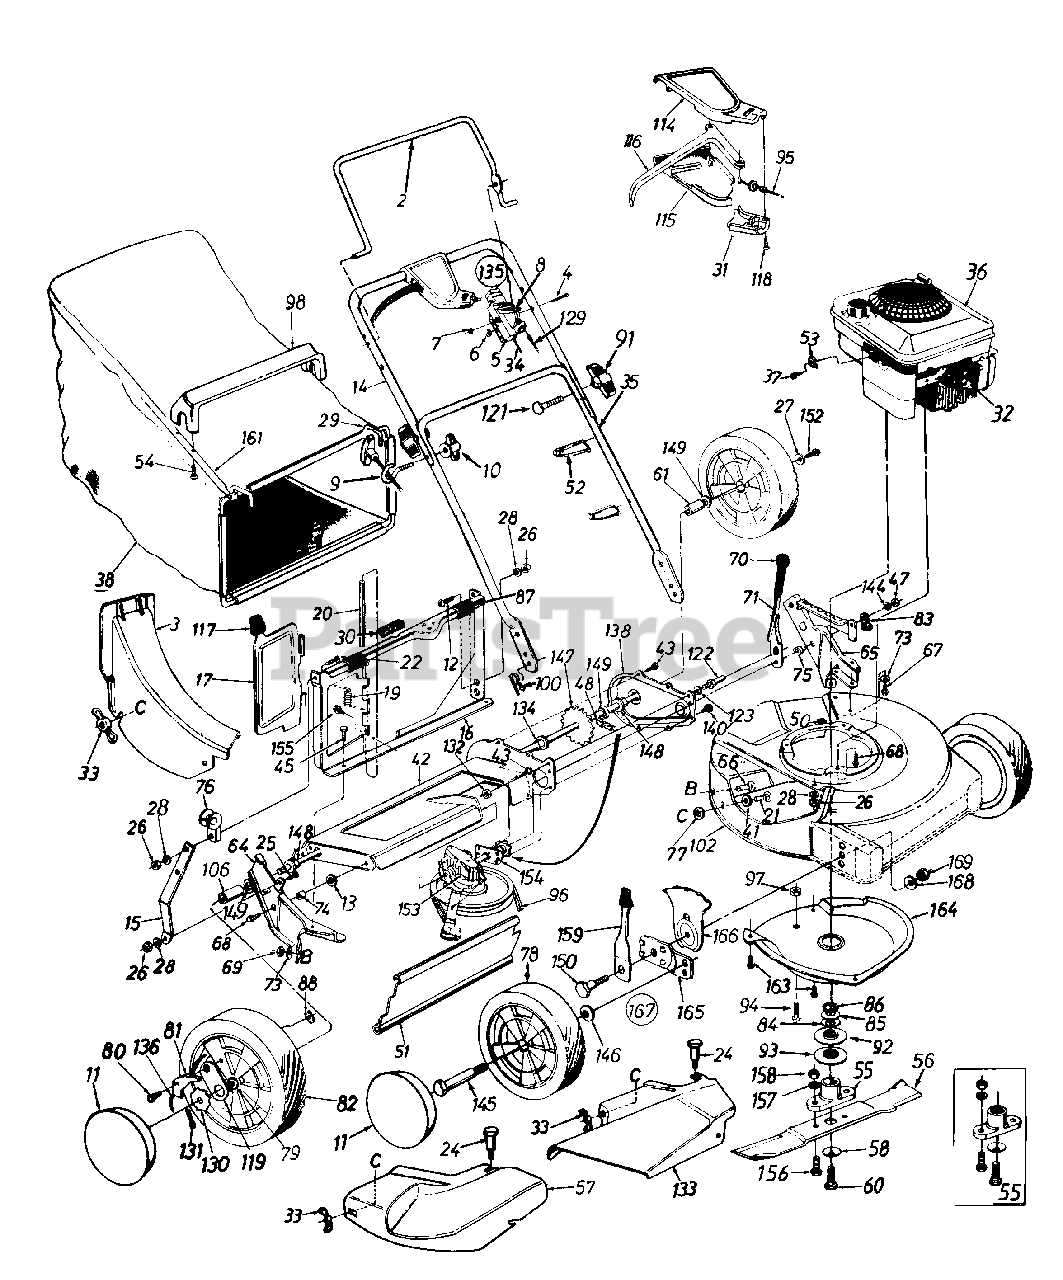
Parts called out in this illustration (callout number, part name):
3	Rear Discharge Chute Ass'y.
4	Oval C-Sunk Scr.
5	Throttle Body
6	Spr. Wash. .66" I.D.
7	Hex L-Nut 1/4-20 Thd.
8	Throttle Lever
9	Rope Guide
10	Wing Nut 1/4-20 Thd.
11	Hub Cap
12	Truss Mach. Scr. 1/4-20 x .62"
13	FL-Wash. .383" I.D. x 1" O.D.
20	Pivot Pin
21	Carriage Bolt 1/4-20 x .62"
22	Truss Mach. Scr. 1/4-20 x 3/4"
24	Shoulder Bolt .312 Dia. x .18 Lg.-Special
25	Hex Bolt 1/4-20 x .62" Lg.
26	Hex Nut 1/4-20 Thd.
27	Bell-Wash. 1/4" I.D.
28	L-Wash. 1/4" I.D.
30	Foam Strip
31	S.P. Control Cover
32	Spark Plug Insulator
33	Wing Nut w/Washer
34	Throttle Control Wire 61"
36	Engine
37	Hex Self-Tap Scr. #10-32 x .62"
38	Grass Bag
41	FL-Wash. .344" I.D. x .62"
45	Hex AB-Tap Scr. 1/4 x .62"
47	Hex Patch L-Nut 3/8-24 Thd.
48	#48 Chain .500" Pitch x 30 Links
51	Rear Flap
52	Cable Tie
53	Cable Clamp
54	Hex AB Scr. #12 x 1.25" Lg.
55	Blade Adapter Kit
56	21" Mulching Blade
57	Mulching Plug
58	Bell-Wash. .39" I.D.
60	Hex Bolt 3/8-24 x 1.5" Lg. (Grade 5)
61	Spacer .513" I.D. x .703" O.D. x .69" Lg.
64	R.H. Handle Wheel Brkt. Ass'y.
65	L.H. Handle Wheel Brkt. Ass'y.
66	Carriage Bolt 5/16-18 x .62"
67	Hex Wash. Hd. B-Tap Scr. 5/16-18
68	Hex Wash. Hd. TT-Tap Scr. 3/8-16
69	Hex Nut 5/16-18 Thd.
71	Height Adj. Lever
73	Bell-Wash. 5/16" I.D.
74	Spacer
75	Shld. Spacer .500" Dia.
76	Rope Guide
77	Bolt Retainer 1/4 x .50" O.D.
78	Front Wheel Ass'y. Comp.
79	Bearing 1/2" I.D.
80	Shld. Scr. 342" Dia. x .268
81	Pawl
82	Rear Wheel Ass'y. Comp.
83	Clamp
84	FL-Wash. .88" I.D.
85	Spr-Washer .89" I.D.
86	Crankshaft Spacer
87	Panel Clip
88	Weld L-Nut 1/4-20 Thd.
91	Hand Knob
92	Pulley Half-Upper
93	Pulley Half-Lower
94	Phil. Mach. Scr. 1/4-20
95	S.P. Cable
96	"V"-Belt
97	Sems Nut 1/4-20 Thd.
98	Bag Handle
100	Hairpin Clip
114	Self-Propelled Control Cover
115	Self-Propelled Control Cover
116	Control Lever
117	Door Grip
118	FL-"C"-Sunk Hd. Tap Scr. #10 x .75" Lg.
119	Pawl Plate
121	Curved Carr. Bolt 5/16-18 x 2" Lg.
122	Shld. Pin 3/8-24 x 1.43" Lg.
123	L-Wash. 3/8" I.D.
129	Control Cable 47" Lg.
130	Ratchet Wheel 1.62" O.D.
131	Cotter Pin 1/8" Dia. x 1.00" Lg.
132	Hex Jam Nut 3/8-24 Thd.
133	Side Chute Deflector Ass'y.
134	Hex Flange Bearing
135	Throttle Box Comp.
136	Spring-Nylon
144	FL-Wash. .385" I.D. x .87"
145	Axle Bolt
146	Bell-Wash. .4" I.D. x .88" O.D.
147	Rear Shaft Ass'y. 21.94" Lg.
148	Hex Flange Bearing .506" I.D. Plastic
149	FL-Wash. .531" I.D. x .930"
150	Shld. Bolt .5" Dia. x . 434"
152	Hex Bolt 1/4-20 x .62" Lg. (Grade 5)
153	Transmission Comp.
155	Hex B-Tap Scr. #10 x .38
156	Hex Scr. 3/8-24 x 1.0" Lg.
157	L-Wash. 3/8" I.D.
158	Hex Nut 3/8-24 Thd.
159	Spring Lever Ass'y. w/knob
163	Hex Wash. Hd. Tap Scr. 1/4 x .38" Lg.
166	Height Adj. Plate
167	Front Height Adj. Ass'y. Comp.-R.H.
168	Bell-Wash. .39" I.D. x 1.38" O.D.
169	Hex Nut 3/8-16 Thd.
